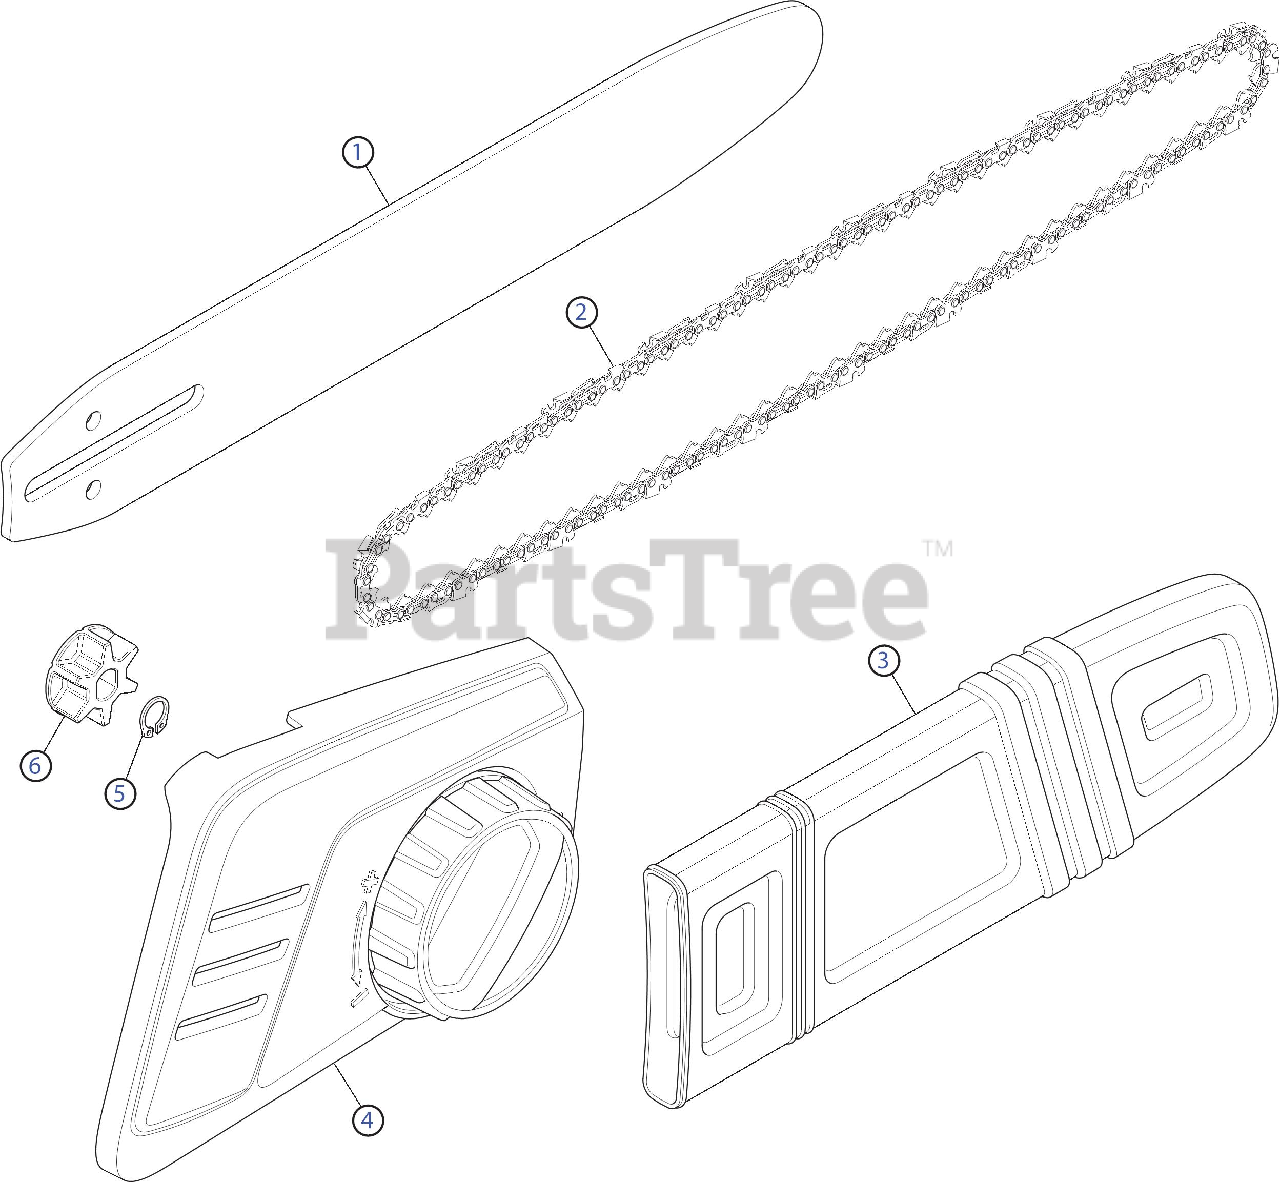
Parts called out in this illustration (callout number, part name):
1	Guide Bar
2	Saw Chain
3	Scabbard
4	Chain Tension / Bar Cover Assembly
6	Drive Sprocket
